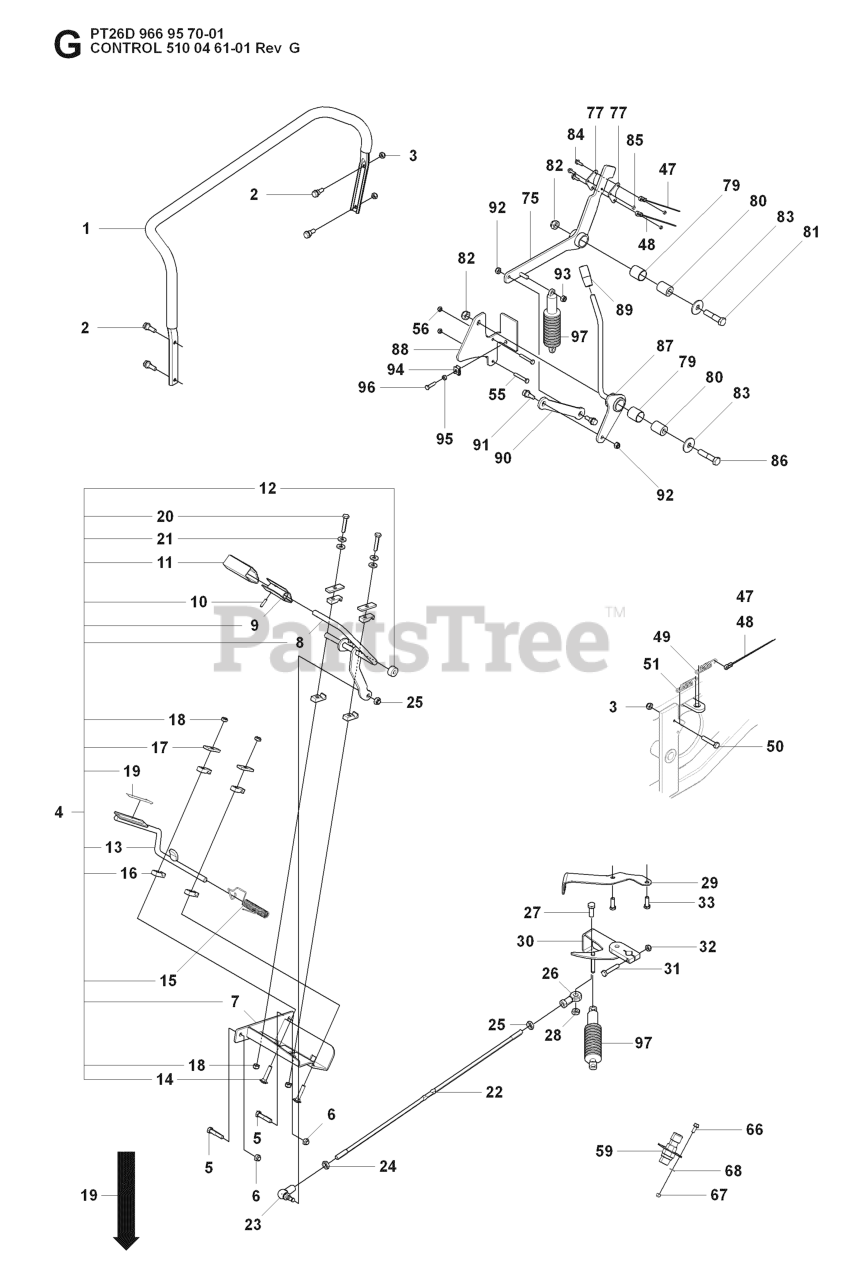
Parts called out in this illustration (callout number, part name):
1	HANDLE ASSY
3	LOCKNUT M8
6	LOCKNUT M8
11	PEDAL RUBBER
14	Screw Mvbf 8 X 40
18	NUT
21	WASHER BRB 8.4X17
25	NUT
28	NUT
31	SCREW
32	LOCKNUT M8
33	SCREW M6S 8X25
50	SCREW
56	LOCKNUT M6
66	Screw
67	LOCKNUT M6
68	WASHER
79	BUSHING
84	SCREW M6S 5X20
85	LOCKNUT M5
92	LOCKNUT M8
97	SHOCK ABSORBER
